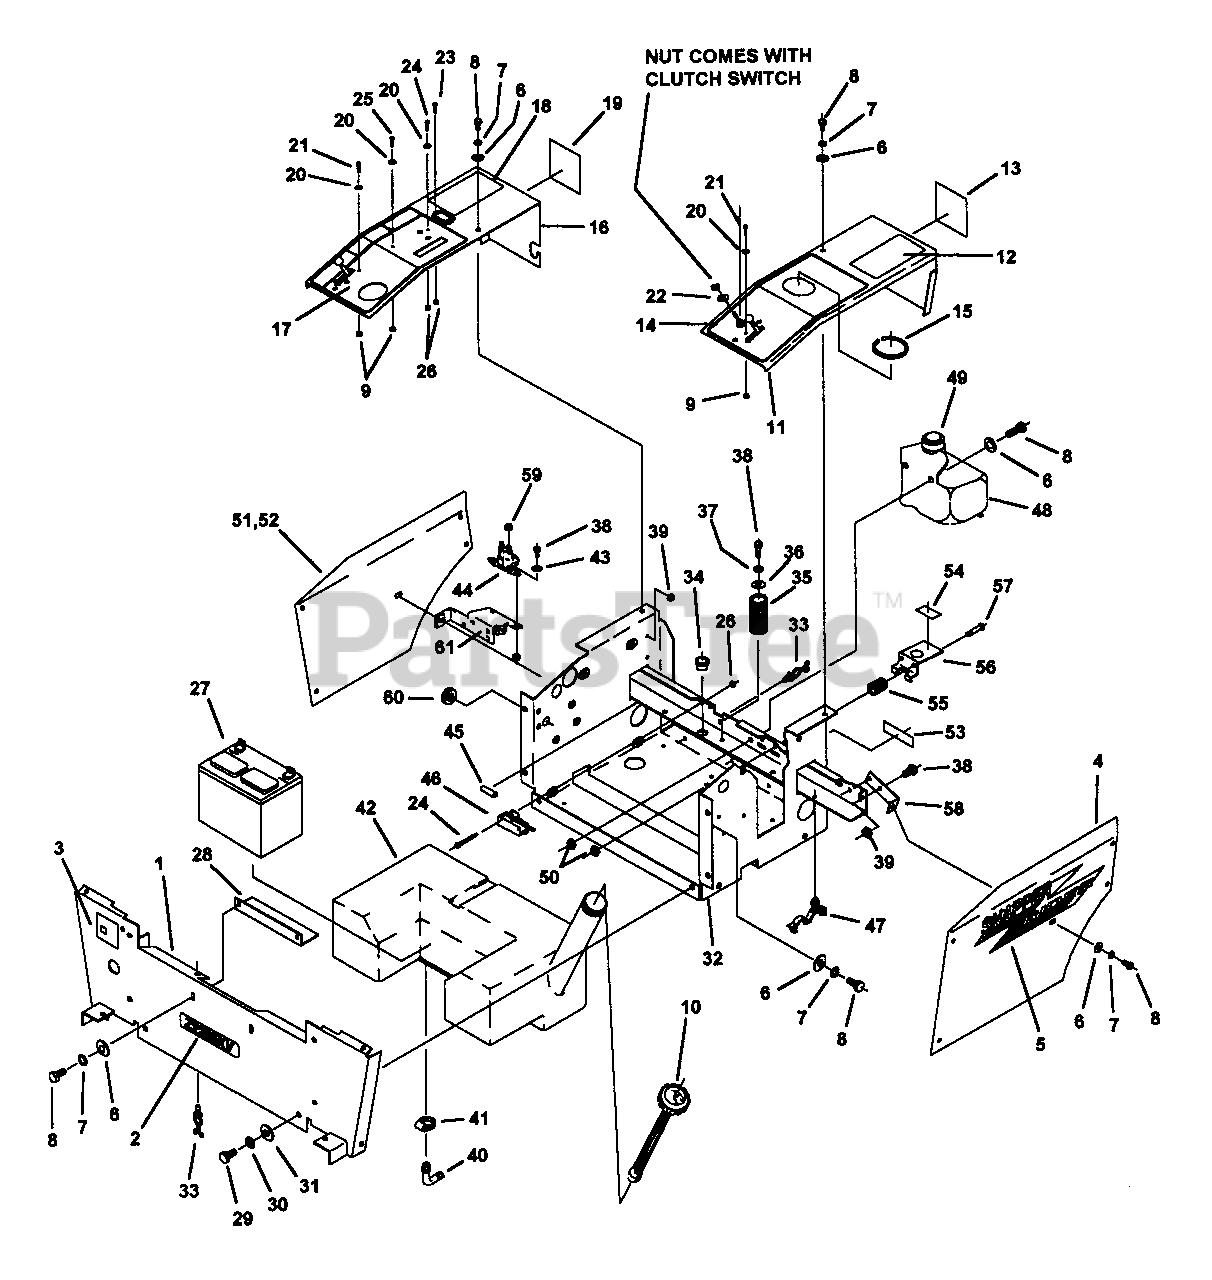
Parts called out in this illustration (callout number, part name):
4	FENDER SKIRT, LH (w/decals)
6	WASHER, FLAT STD. 5/16"
7	LOCKWASHER, 5/16" HEAVY SPRING
8	BOLT, 5/16-18 X 3/4" GR. 5
10	FUEL GAUGE CAP
12	DECAL, CAUTION
13	DECAL, FREEWHEEL MACHINE
15	TRIM, U-CHANNEL GAS TANK
16	FENDER CAP (w/decals) RH
19	DECAL, HYDRO DRIVE BELT
23	SCREW, MACHINE, #6-32 X 5/8"
24	SCREW, MACHINE, #6-32 X 1"
27	BATTERY 12 VOLT
28	BATTERY CLAMP ANGLE
29	NUT, HEX JAM, 3/4-16 UNF
30	LOCKWASHER, 3/8 HEAVY SPRING (B)
31	WASHER,FLAT STD. 3/8"
32	SEAT SUPPORT WELDMENT
33	BLINDHOLE KURLY, LOC
34	BUSHING, PLASTIC
35	SEAT SPRING
37	LOCKWASHER, 1/4" SPLIT SPRING
38	BOLT, 1/4-20 X 3/4 GR.5
39	LOCKNUT, 1/4-20 NYLOC
40	ELBOW, 90D 1/4NPT X 1/4 BARB
42	FUEL TANK
43	WASHER, FLAT STD. 1/4"
44	SOLENOID, STARTER, 12V. INT. GRD.
45	EDGE GUARD
46	SWITCH, ENCL, SPDT 15A HINGED LEVER
47	FITTING 1/2" ROSE BUD CLIP
48	TANK, 1.5 QT. CHARGE PUMP
49	CAP, OIL TANK
50	NUT, HEX. 5/16-18 NYLOC
51	FENDER SKIRT, RH (w/decals)
54	DECAL, "PULL TO RELEASE..."
55	SPRING, COMPRESSION, .5 O.D. X .625 X .65
56	LATCH PLATE
57	BOLT, 5/16-18 X 1-3/4" GR.5
58	SKIRT BRACKET, FENDER
59	NUT, 5/16-24 UNF, GR. 5 PLATED
